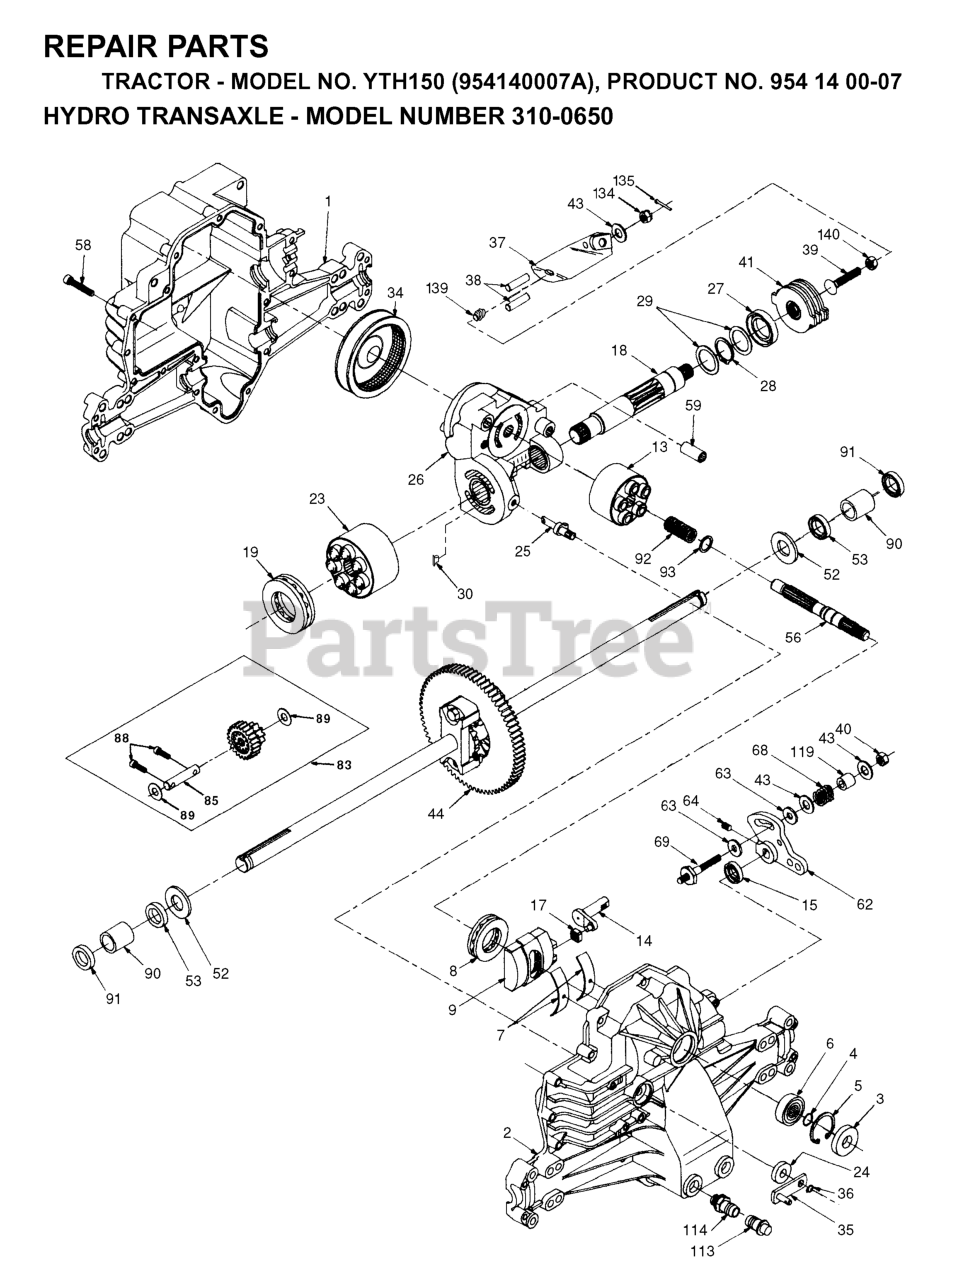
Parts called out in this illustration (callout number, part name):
1	LOWER HOUSING
2	HOUSING UPPER 70255
3	SEAL.LIP.H-G.(9008000-0128)
4	RING RETAINING 2003016
5	RING.RETAINING.(2003052)
6	BALL BEARING
7	CRADLE BEARING
8	BEARING, THRUST 50551
9	SWASHPLATE (2003087)
13	BLOCK, CYL ASSY
14	TRUNNION ARM
17	SLOT GUIDE
18	SHAFT, MOTOR
19	BEARING, THRUST 50552
23	BLOCK, CYL ASSY
25	BYPASS ACTUATOR
26	CENTER SECTION ASS'Y KIT
28	RETAINING RING
34	ELEMENT, OIL FILTER
35	BYPASS ARM
36	RETAINING RING 44870
37	ACTUATING ARM
38	ACTUATING PIN 44891
39	BOLT 5/16-24 X 1-3/4
40	LOCKNUT, HEX 5/16-24
41	BRAKE ROTOR 70135 HYDRO-GEAR
43	WASHER .34X.88X.06.44130
44	KIT SVC DIFFRENTIAL 70130
52	WASHER.HYDRO-GEAR 44875
53	SEAL.HYDRO.53901
56	SHAFT.INPUT.50005
58	BOLT #44876
62	CONTROL ARM 50254
63	DAMPENER PUCK
64	SCREW.SET.50018
68	SPRING HELICAL COMP 50277
69	STUD 5/16-24 50284
83	JACK SHAFT ASSY
89	WASHER 50132
90	SLEEVE.BEARING 50118
91	RP SEAL, WIPER
92	SPRING 2003014
113	CAP, VENT ASSY
114	O-RING KIT 70110
119	SPACER.HYDRO GEAR 50278
134	NUT.CAS.HYD.44142
135	ID DOT HYDD
139	SPRING, COMPRESSION 50431
140	NUT, HEX 5/16-24
